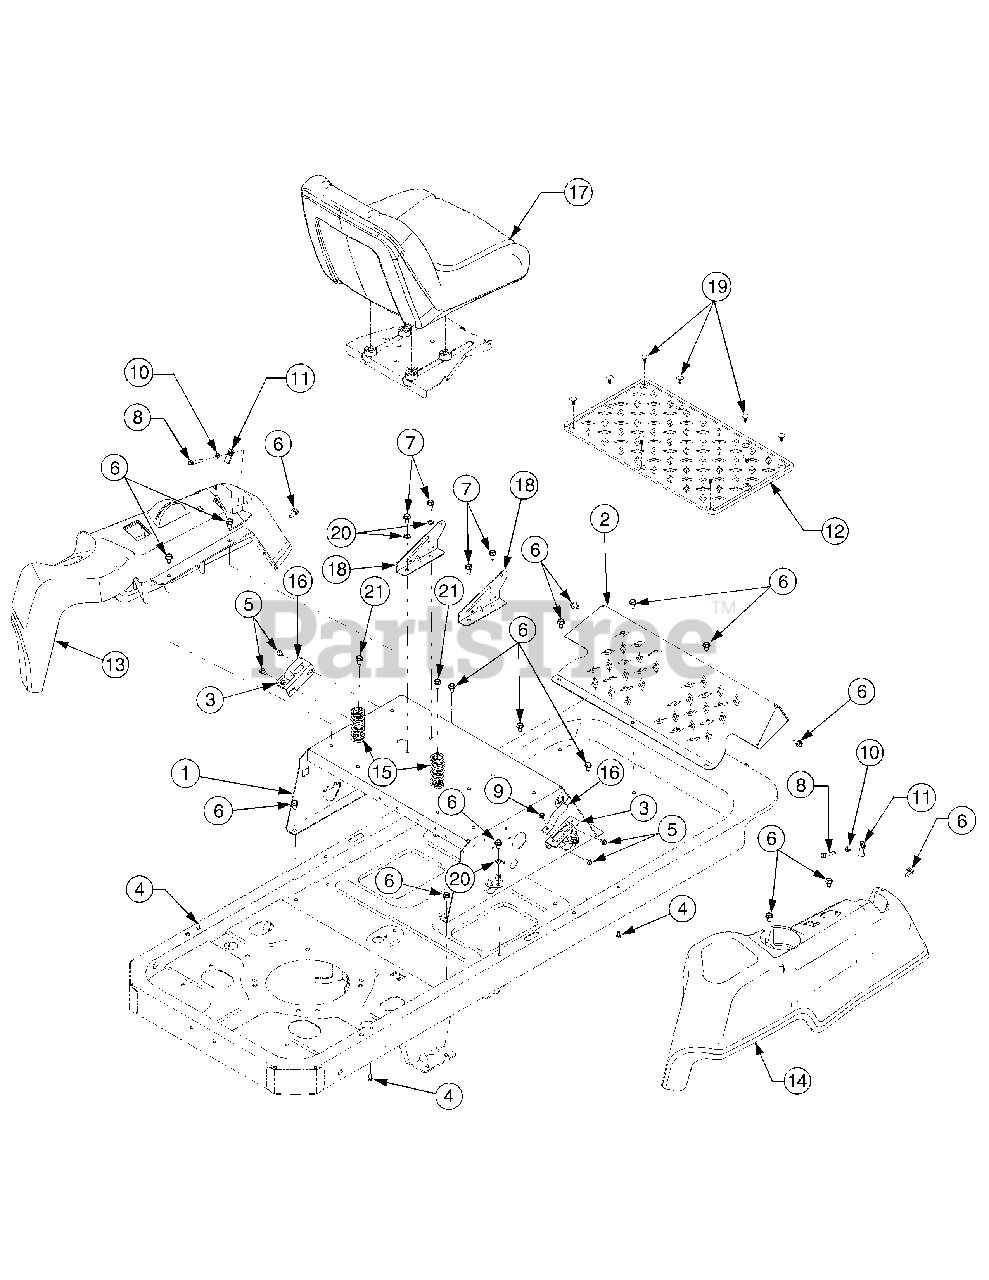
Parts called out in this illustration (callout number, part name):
4	Screw, Hex Wash. Hd Tapp #12-16 x .50
5	Screw, Hex Wash. Hd. Tapp. 1/4-20 x .5
6	Screw, Hex Wash. Hd. Tapp 5/16-18 x .625
7	Screw, Hex Wash. Hd. Tapp 5/16-12 x .75
8	Screw, Hex Wash. Hd. Tapp. 1/4-20 x 1.5
9	Screw, Hex Wash. Hd Tapp #10-16 x .375
10	Nut, Hex Jam, 1/4-20 GR2
11	Nut, U Type Speed, 1/4-20
12	Pad, Foot
13	Console, LH
14	Console, RH
14	Graphic, Instruction
14	Graphic, Cub Cadet
15	Spring, Compression, 1.28 x 3.125
16	Spring, Switch Actuator
19	Clip, Ratchet
20	Washer, External Tooth, 3/8
21	Screw, Hex Wash. Hd. Tapp 5/16-18 x .75
